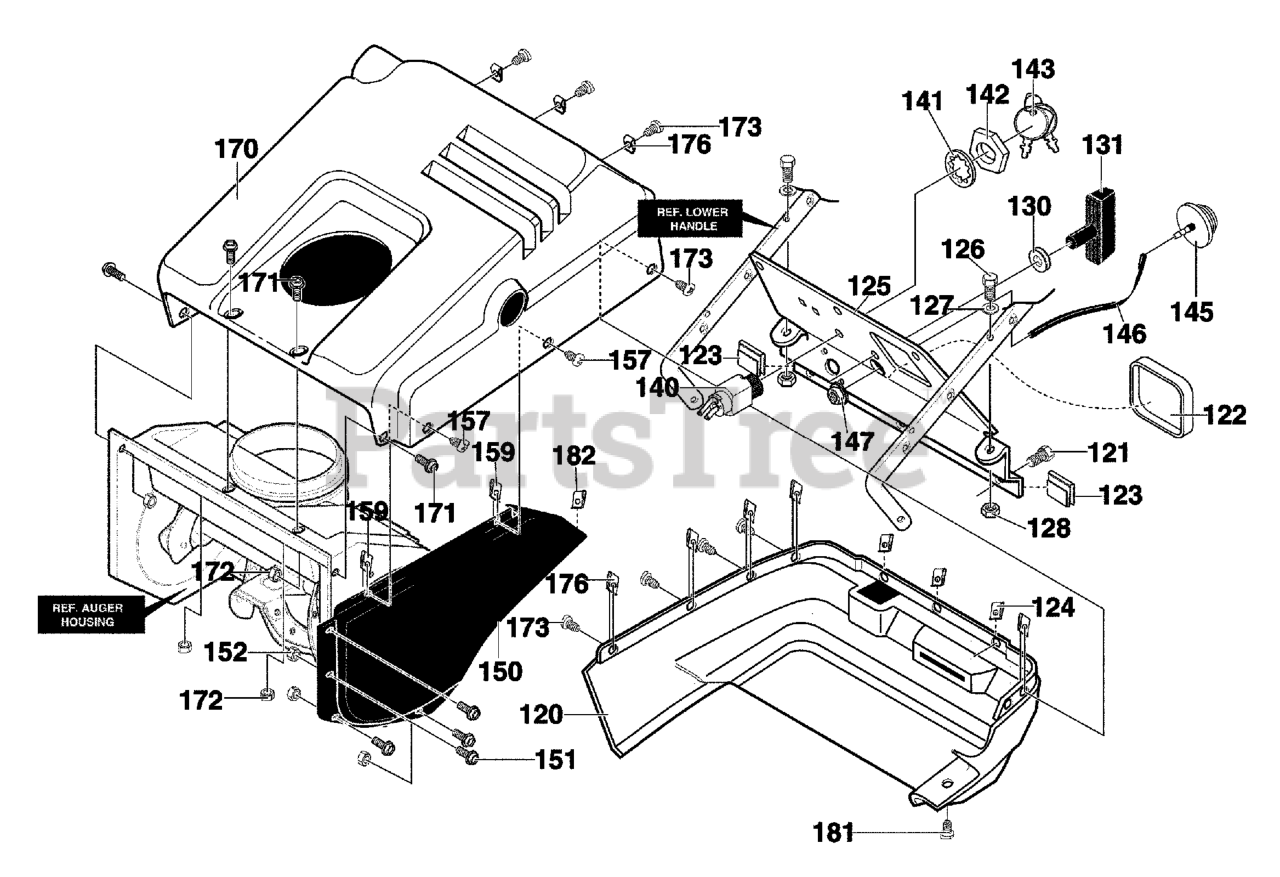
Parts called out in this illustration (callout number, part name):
120	COVER, BOTTOM
121	SCREW, 1/4-14X.75
122	PANEL, SPARK ACCESS
123	CLIP, S TINNERMAN
124	NUT, 1/4-10 SPEED J TYPE
125	CONTROL PANEL
126	SCREW, 1/4-20X1.25
127	FLATWASHER, .281X.63X.065
128	NUT, 1/4-20 REGHEXCTRLK
130	GOMMET & WASHER
131	KNOB T
140	SWITCH, IGNIT.
141	WASHER, REGINTLK .640X1.1X.05
142	NUT. 5/8-32
143	KEYS & RING
145	PRIMERBULB
146	HOSE PRIM 9.50LG
147	NUT, 1/4-20 REGHEXKEPS
150	COVER, BELT
151	SCREW, 10-24X.50
152	NUT, #10-24 REGHEXCTRLK
157	SCREW, 1/4-14X.75
159	NUT, 1/4-10 SPEED J TYPE
170	COVER, TOP
171	SCREW,#10-24X.50
172	NUT #10-24 REGHEXCTRLK
173	SCREW, 1/4-14X.75
176	NUT, 1/4-10 SPEED J TYPE
181	SCREW, 1/4-14X.75
182	NUT 1/4-10 SPEED J TYPE
